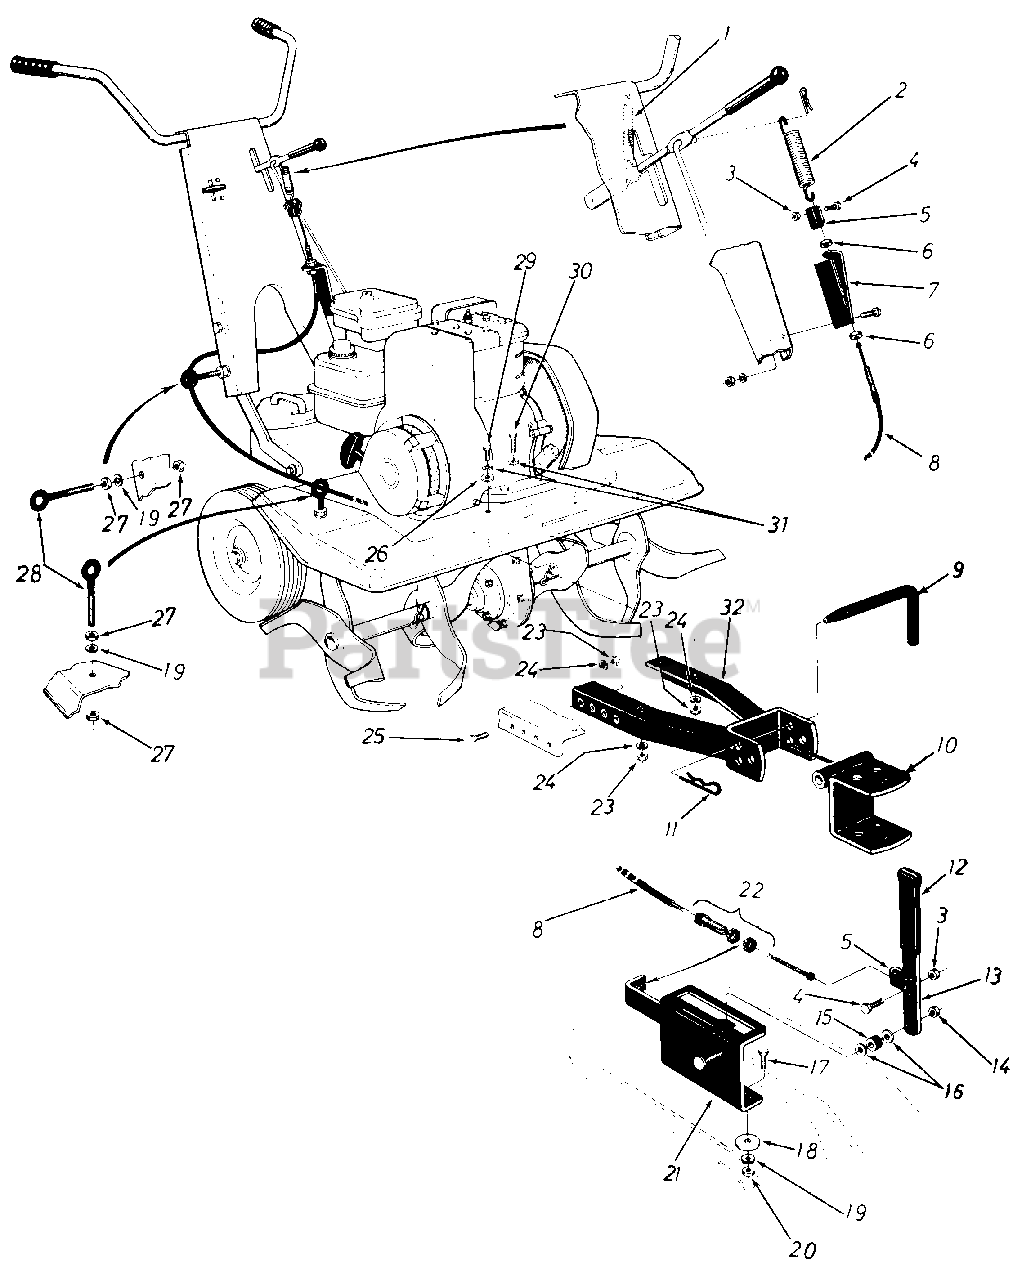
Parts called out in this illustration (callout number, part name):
1	Spring 2-1/2" Lg.
2	Spring 3-1/2" Lg.
3	Hex Cent. L.-Nut 1/4-20 Thd.
4	Hex Scr. 1/4-20 x .62" Lg.*
5	Clevis Fitting
6	Hex Jam Nut 5/16-24 Thd.*
7	Bracket
8	Control Cable
9	Hitch Pin
10	Hitch Bar Brk't. Ass'y.
11	Hair Pin Cotter
13	Shift Grip
14	Hex Cent. L.-Nut 5/16-18 Thd.*
15	Rubber Washer
16	Fl.-Wash. .344 I.D.
17	Hex Scr. 3/8-16 x 1.00" Lg.*
18	Fl.-Wash. .406 I.D.
19	L. Wash. 3/8" I.D.*
20	Hex Cent. L.-Nut 3/8-16 Thd.
21	Engagement Lever Brk't.
22	Adjustment Ferrule
23	Hex Nut 5/16-18 Thd.*
24	L.-Wash. 5/16" I.D.*
25	Hex Scr. 5/16-18 x .75" Lg.*
26	Fl.-Wash. .344" I.D.
27	Hex Nut 3/8-16 Thd.*
28	Eye Bolt
29	Hex Scr. 5/16-18 x 1.00" Lg.*
30	Hex Scr. 5/16-18 x 2.00" Lg.*
31	External L.-Wash. 5/16" I.D.*
32	Tiller Hitch Ass'y.
